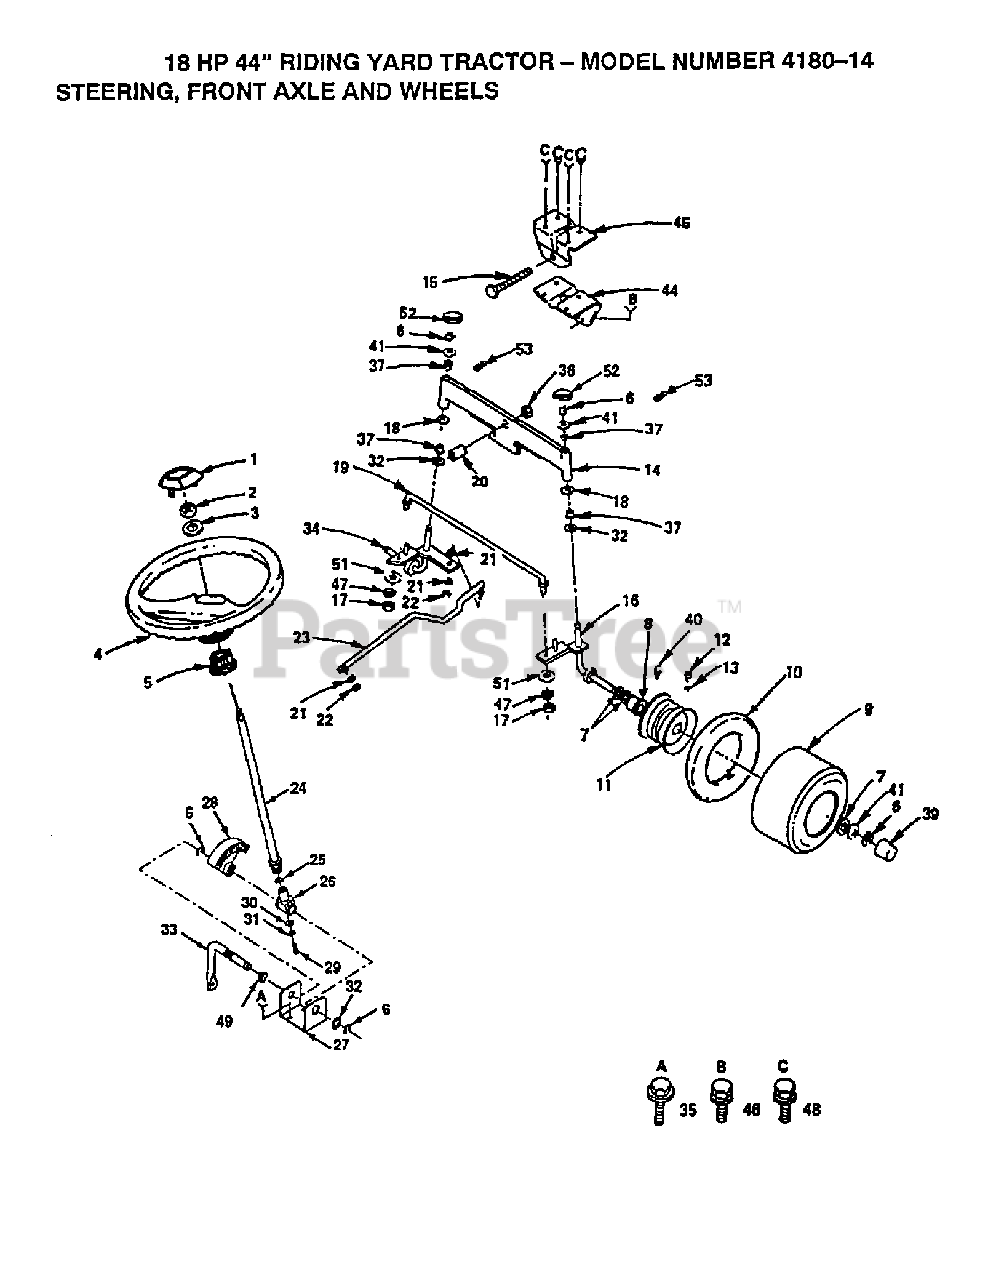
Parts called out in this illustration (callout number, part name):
1	INSERT STR WHL
2	NUT.HEX.1/2-20
4	Steering Wheel
6	RING CLIP
8	BEARING T
9	TIRE HEAVY DUTY
10	TUBE.5.3/4.5/6
11	RIM.ASM.6".FRONT.SILVER
12	VALVE STEM LT
13	VALVE CAP
14	AXLE ASSY T
16	SPINDLE-RH LT
17	LOCKNUT
21	WASHER, LOCK 3/8
22	NUT
24	SHAFT ASS'Y STEER
25	THRUST WASHER
26	SHAFT,SUPPORT
27	BRKT,STEERING
28	GEAR,SECTOR
30	WASHER
31	LOCKWASHER
33	SHAFT,PITMAN
34	SPINDLE-LH LT
36	LOCK NUT
37	BEARING.STEERING.COLUMN
39	CAP.HUB.FRONT.LT.BLACK
40	FITTING LT
44	SUP-SADDLE FRT LT
45	SUPPORT-SADDLE LT NLA
46	SCREW LT
47	LOCKWASHER
48	SCREW SPECIAL
49	NYLINER T (7283A)
51	WASHER M
52	CAP.SPINDLE.BLACK
53	ZERK.GREASE.TAPERED
62	WASHER THRUST
